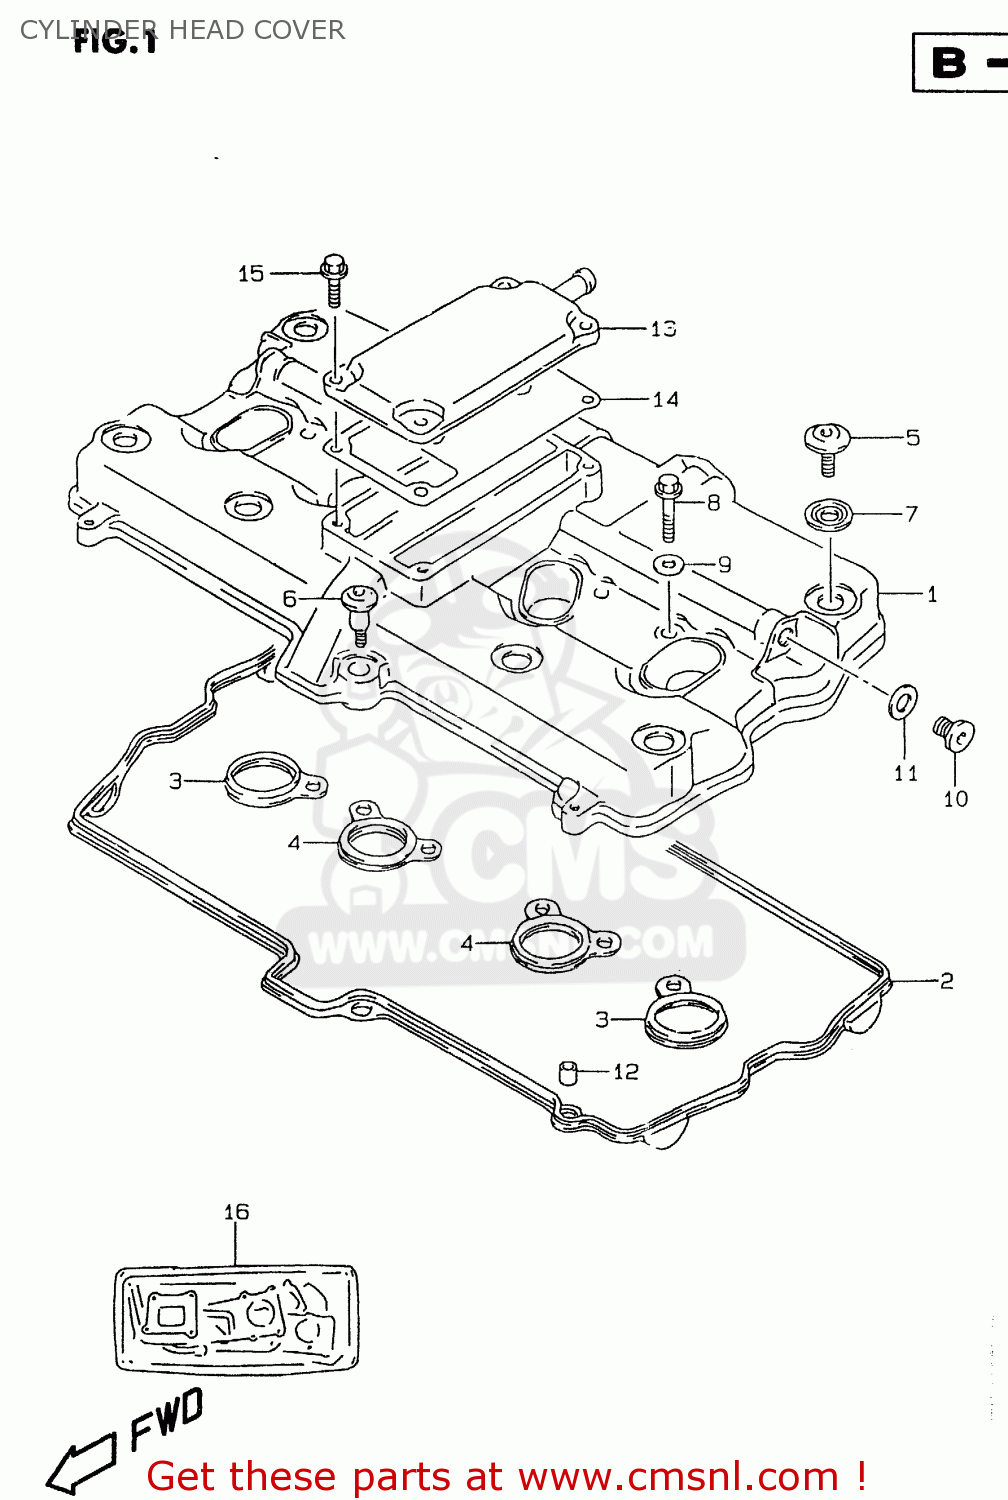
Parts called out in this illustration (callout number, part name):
1	COVER,CYLINDER HEAD
2	GASKET,CYLINDER HEAD COVER (NAS)
3	GASKET,HEAD COVER NO.2 (NAS)
4	GASKET,HEAD COVER NO.3 (NAS)
5	BOLT(7X17.5)
6	BOLT(7X31)
7	WASHER(10.6X25.5X2.3)
8	BOLT,UNION 8X35
9	GASKET 8.2X14X1 (NAS)
10	PLUG(L:12)
11	GASKET(12.1X16.2X3.7) (NAS)
12	PIN
13	COVER,BREATHER
14	GASKET,BREATHER COVER (NAS)
15	BOLT
16	GASKET SET
